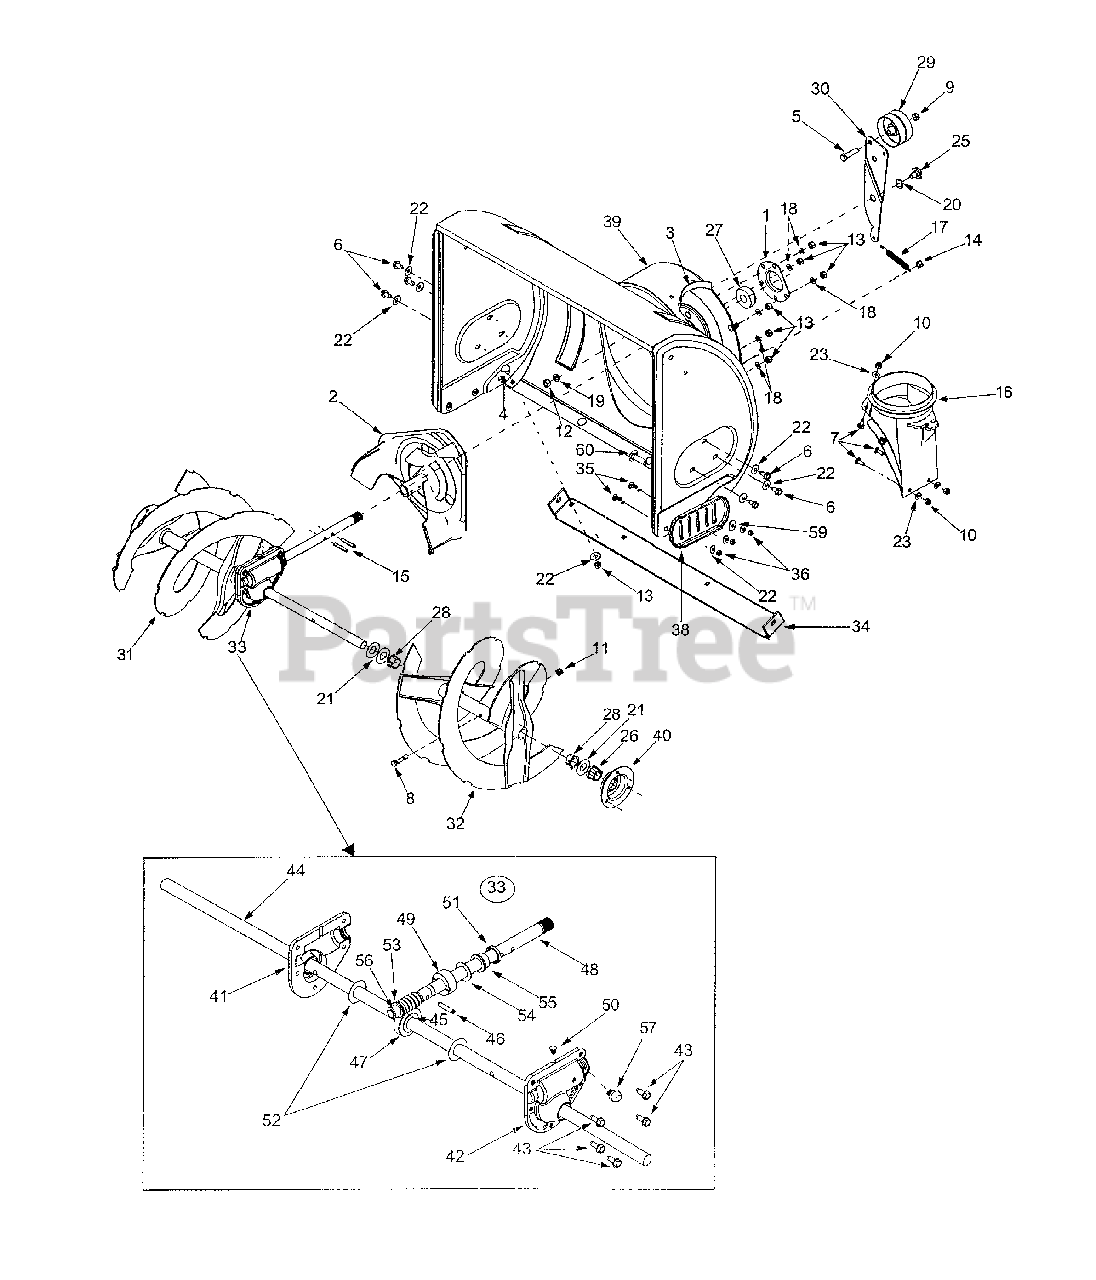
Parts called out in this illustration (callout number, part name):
1	Bearing Housing
4	Carriage Bolt 5/16-18 x .75" Gr.2
5	Hex Screw 3/8-24 x 1.5" Gr.5
6	Hex Screw 5/16-18
7	Carriage Screw 1/4-20 x .75"
8	Shear Bolt 5/16-18 x 1.5"
9	Jam Nut 3/8-24
10	Hex Lock Nut 1/4-20
11	Hex Lock Nut 5/16-18
12	Hex Nut 3/8-16 Gr.2
13	Hex Nut 5/16-18 Gr.5
14	Hex Patch Nut 5/16-18
15	Spiral Pin
16	Chute Adapter
17	Extension Spring
18	Lock Washer
19	Lock Washer
20	Wave Washer
21	Flat Washer
22	Belleville Washer
23	Flat Washer
25	Shoulder Screw
26	Hex Flange Bearing
27	Flange Ball Bearing
28	Flange Bushing
29	Flat Idler
35	Carr. Bolt: 5/16-18 x 0.75
36	Hex Nut: 5/16-18 Gr.5
41	RH Housing
42	LH Housing
43	TT Screw, 1/4-20 x .75
44	Spiral Axle, 26"
45	Hi-Pro Key, 3/16 x 5/8
46	Spring Spiral Pin, .25 x 1.25
47	Worm Gear, 20T
48	Worm Shaft
49	Thrust Collar
50	Grease Plug
51	Grease Seal
52	Flat Washer .76 x 1.5 x .030
53	Flat Washer .508 x 1.0 x .020
54	Flat Washer .76 x 1.5 x .060
55	Flange Bearing .75 x 1.0 x .59
56	Flange Bearing .503 ID x .75 OD
57	Grease Fitting
59	Flat Washer
60	Carriage Screw: Special
